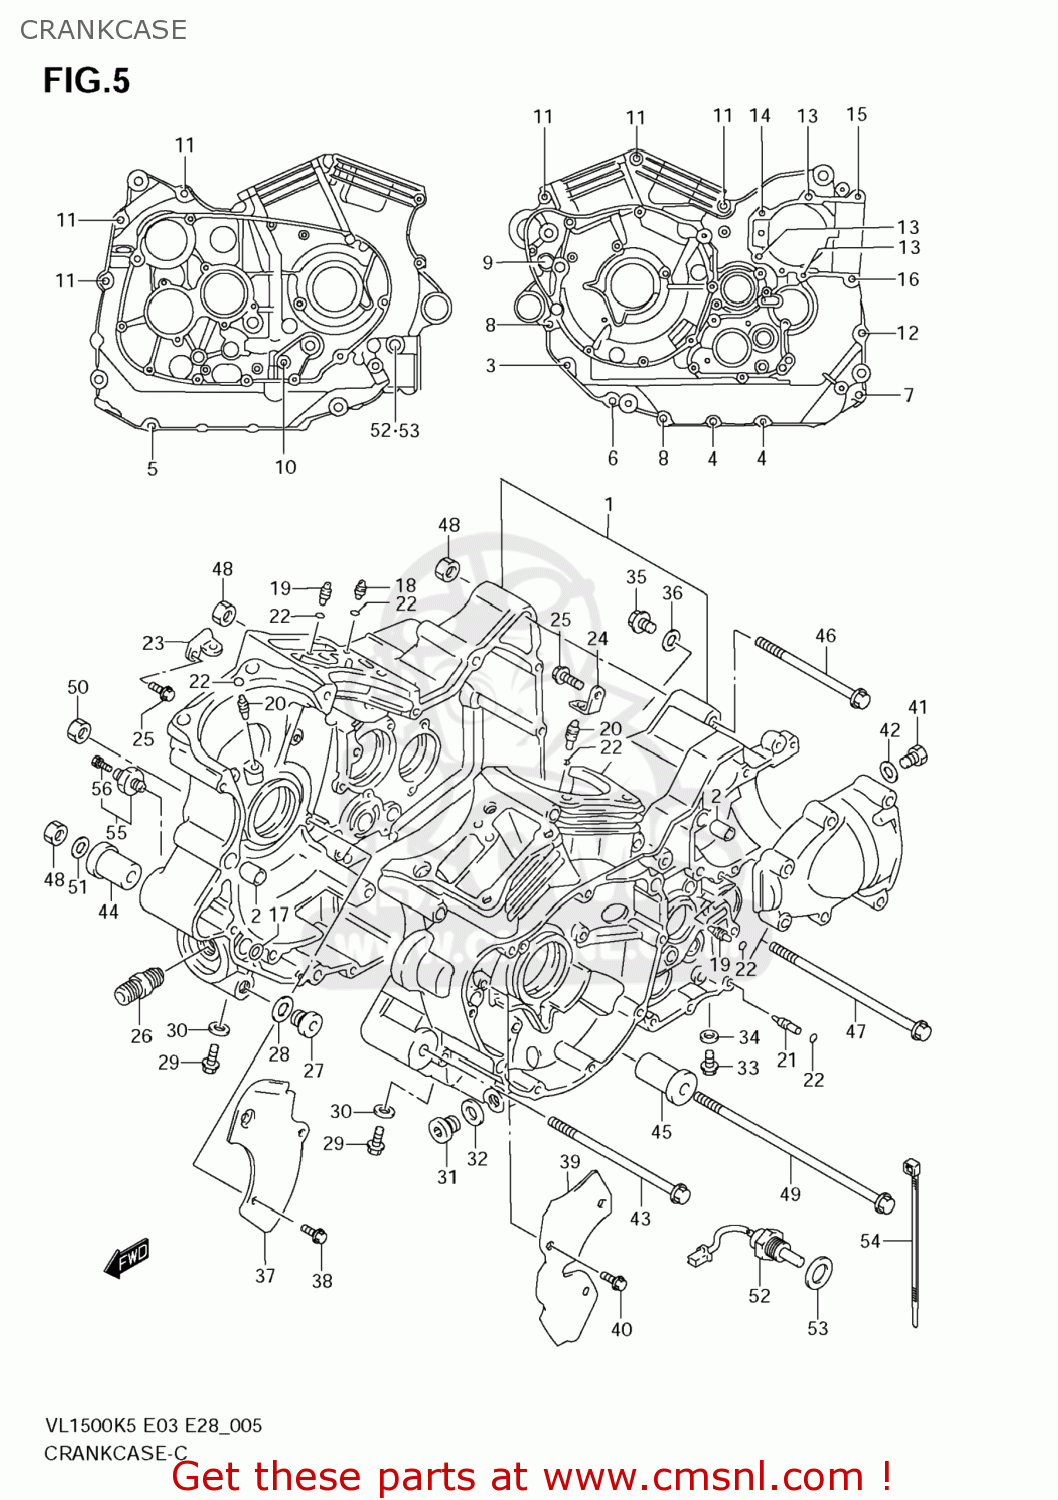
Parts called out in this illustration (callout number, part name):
1	CRANKCASE SET
2	PIN(8.4X11X20)
3	BOLT
4	BOLT
5	BOLT
6	BOLT
7	BOLT
8	BOLT
9	BOLT
10	BOLT(8X115)
11	BOLT(8X95)
12	BOLT
13	BOLT
14	BOLT
15	BOLT
16	BOLT
17	O RING(D:1.9,ID:12.6)
18	JET(2.2)
19	JET,AIR(14)
20	JET,PISTON COOLING(0.8)
21	JET,MISSION OIL(1.4)
22	O RING(D:1.2,ID:4)
23	PLATE,PISTON JET FR
24	PLATE,PISTON JET RR
25	BOLT
26	UNION,OIL STAND
27	PLUG,16X8
28	GASKET(16X22X2) (NAS)
29	BOLT
30	GASKET(8.2X14X1) (NAS)
31	PLUG,14X12
32	GASKET(13.8X18.8X4.8) (NAS)
33	BOLT
34	GASKET(5.8X13X1.2) (NAS)
35	PLUG(12X10)
36	GASKET(12.1X16.2X3.7) (NAS)
37	PLATE,OIL SEPARATOR
38	BOLT(6X12)
39	PLATE,OIL SEPARATOR FR
40	BOLT
41	PLUG,12X20
42	GASKET(12.1X16.2X3.7) (NAS)
43	BOLT(10X205)
44	SPACER,ENG MTG
45	SPACER,ENGINE MOUNT(L27)
46	BOLT(10X140)
47	BOLT(10X160)
48	NUT
49	BOLT(10X265)
50	NUT
51	WASHER (10.5X20X3.2)
52	SENSOR,OIL TEMP
53	GASKET(14X20X1.5) (NAS)
54	CLAMP(L:145)
55	SWITCH ASSY,OIL PRESSURE
56	BOLT,OIL PRESSURE SWITCH
